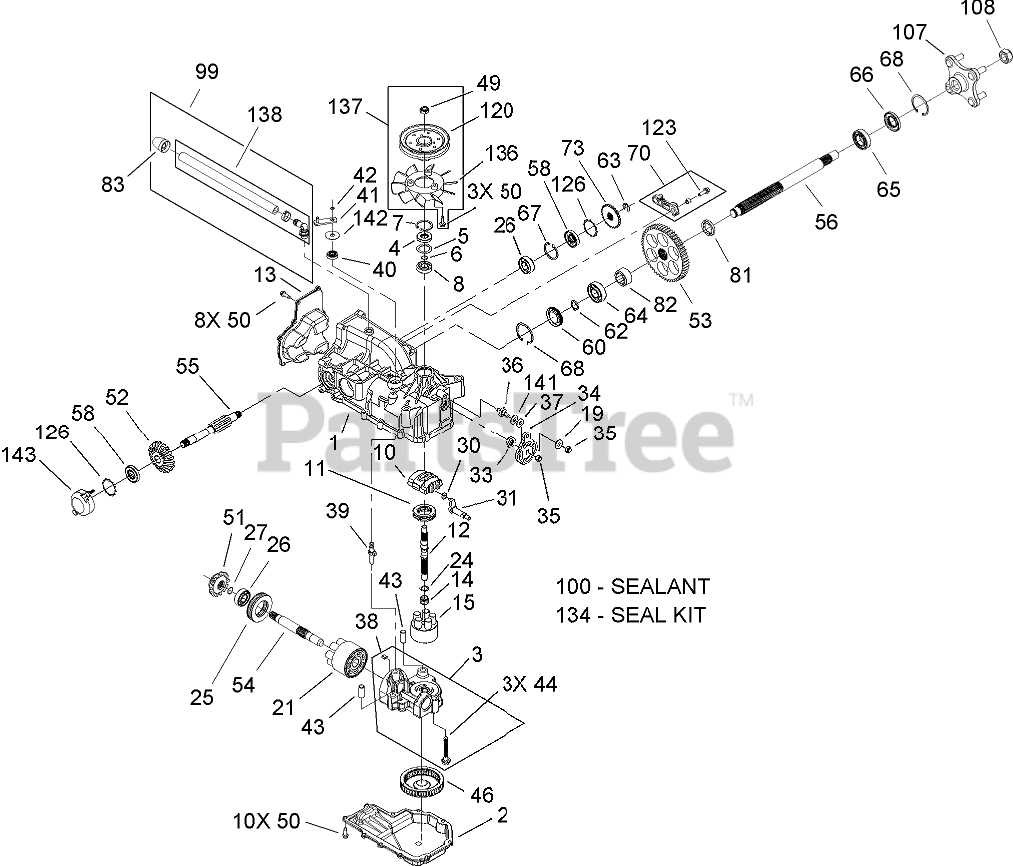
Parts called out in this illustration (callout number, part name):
1	Main Housing Kit
2	Housing-Lower
3	CENTER SECTION KIT ASM
4	SEAL-LIP
5	SPACER
6	RING-WIRE, RETAINING
7	RING-RETAINING
8	BEARING-SHAFT, BALL
10	SWASHPLATE-VARIABLE
11	BEARING-THRUST
12	Shaft-Input
13	COVER-BACK
14	SPRING-BLOCK
15	CYLINDER BLOCK ASM
19	WASHER-PIVOT
21	CYLINDER BLOCK ASM
24	WASHER-THRUST
25	BEARING-THRUST
26	BEARING-BALL
27	RING-RETAINING
30	GUIDE-SLOT
31	TRUNNION ASM
33	SEAL-LIP
34	ARM-CONTROL
37	PUCK-FRICTION
38	PLATE-BYPASS
39	ACTUATOR-BYPASS
40	SEAL-LIP
41	ARM-BYPASS
42	RING-RETAINING
46	FILTER
49	NUT-LOCK
51	GEAR-BEVEL, 14T
52	GEAR-BEVEL, 19T
53	GEAR-BEVEL, 53T
54	SHAFT-MOTOR
55	SHAFT-BRAKE
56	SHAFT-AXLE
58	SEAL-LIP
60	PLUG-SIDE SEAL
62	RING-AXLE, RETAINING
63	RING-RETAINING
64	Bearing-Ball
65	BEARING-BALL
67	RING-RETAINING
68	RING-RETAINING, AXLE
70	LH BRAKE ARM ASM
73	DISC-BRAKE
81	BUSHING-AXLE
82	BUSHING-AXLE
83	CAP VENT ASM
99	Breather Kit
107	HUB ASM
120	PULLEY
123	SCREW-HHF
126	RING-RETAINING
136	FAN
137	FAN PULLEY KIT
138	Hose/Fitting ASM
141	Washer
142	Washer
143	Cover-Brake, Plastic
